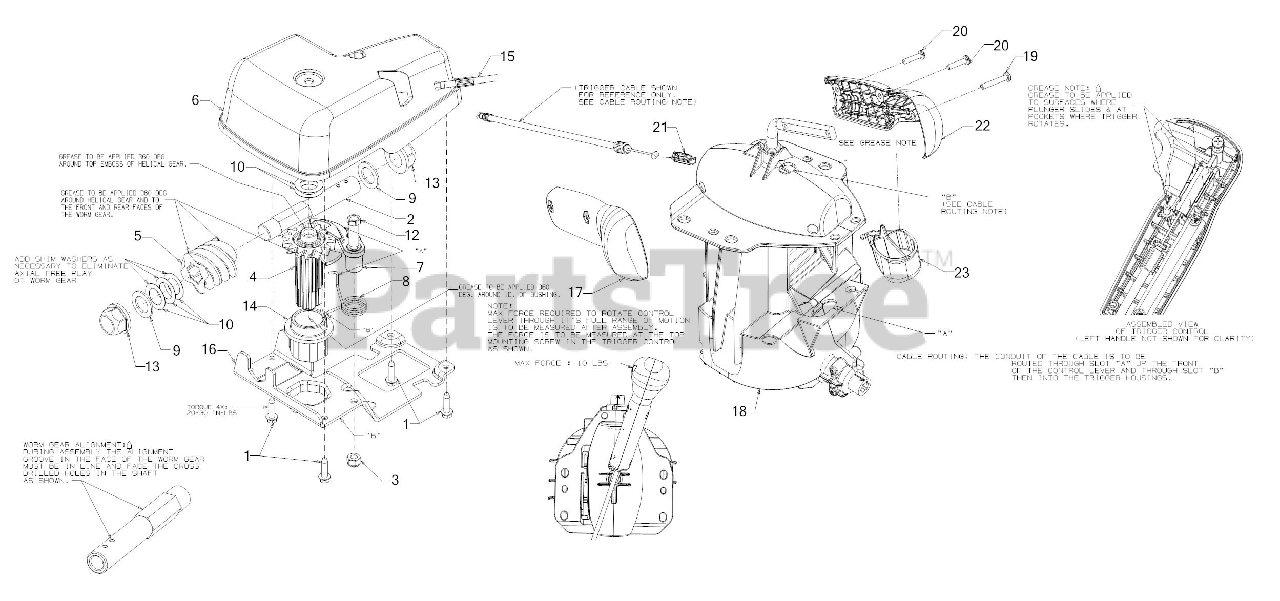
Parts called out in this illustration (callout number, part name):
1	SCREW #12-16 .75
2	WORM DRIVE SHAFT .625
4	HELICAL GEAR-14T
5	WORM GEAR
6	CHUTE GEARBOX COVER
7	CHUTE LOCK PAWL
8	TORSION SPRING
9	FLAT WASHER
10	SHIM WASHER .632X1.000X.010:HD
12	SHOULDER BOLT
13	FLANGE BEARING
14	HEX FLANGE BEARING
15	CHUTE LOCK CABLE
16	CHUTE ROTATION BRACKET
17	TRIGGER HOUSING KIT
18	CHUTE CONTROL SHAFT ASSEMBLY
19	SCREW #8 x 1.0
20	SCREW #8-32 x .750
21	CABLE PLUNGER SLIDE
22	TRIGGER HOUSING KIT
23	JOYSTICK TRIGGER
